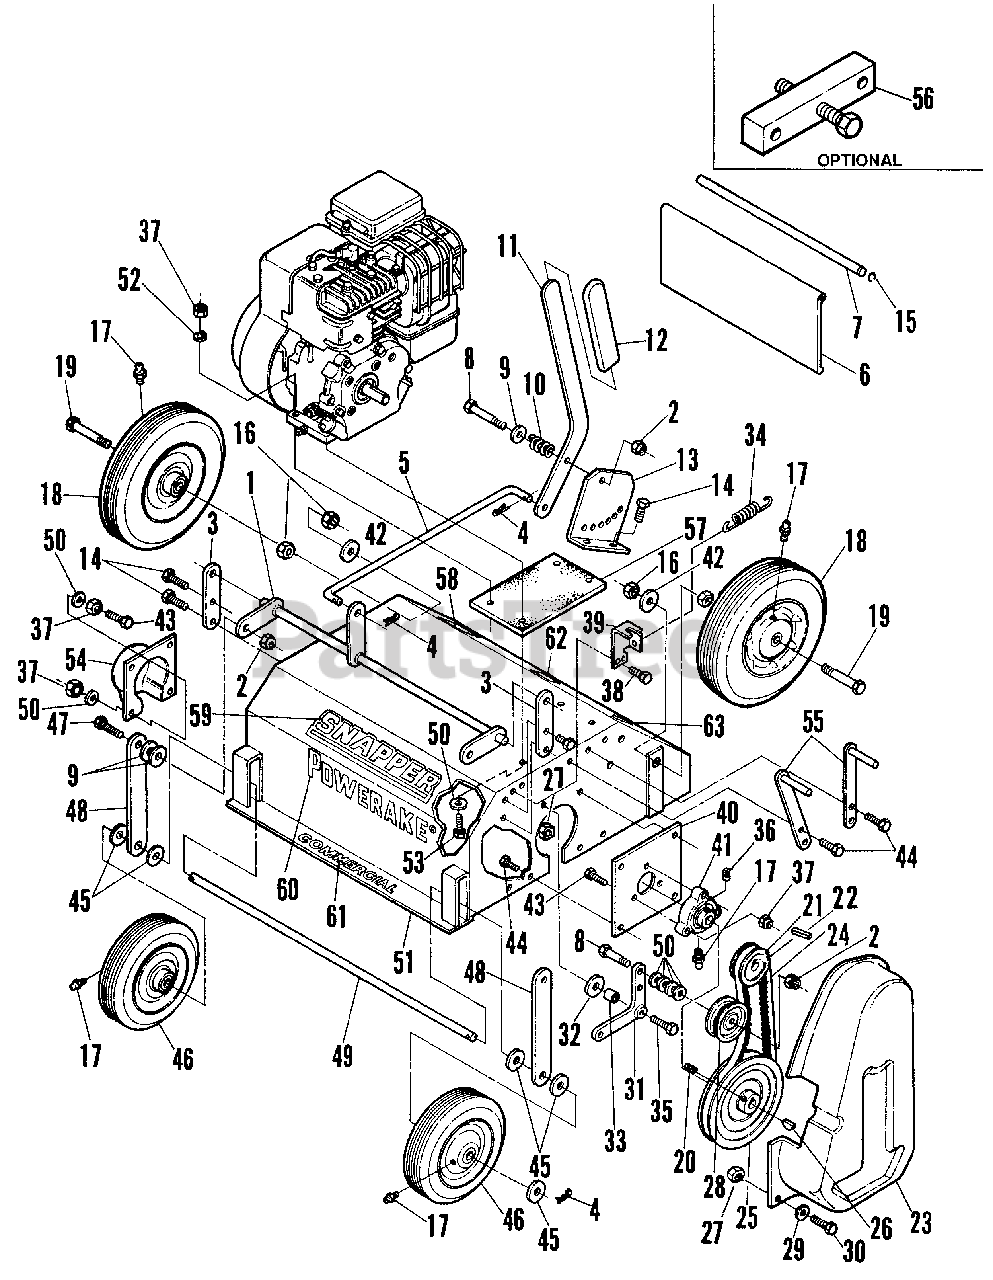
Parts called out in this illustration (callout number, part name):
1	ROD, Height Adjustment, Complete
2	NUT, 3/8-16 Hex Nyloc
3	ARM, Pivot
4	PIN, 1/8 x 3/4" Cotter
5	ARM, Linkage
6	DEFLECTOR
7	ROD, Deflector
8	SCREW, 3/8-16 x 2" Hex Head Cap, Grade 5
9	WASHER, 3/8" Standard Flat
10	SPRING, Compression
11	ADJUSTMENT LEVER w/Grip
12	GRIP, Adjustment Lever
13	GAUGE, Adjustment
14	SCREW, 3/8-16 x 1" Hex Head Cap, Grade 5
15	RING, 5/16 External Retaining
16	NUT, 5/8-11 Hex Jam
17	FITTING, 1/4-28 Straight Grease
18	REAR WHEEL, 10" w/Grease Fitting. (7-6998)
19	SCREW, 5/8-11 x 4" Hex Head Cap, Grade 2
20	SCREW, 5/16-18 x 3/8" Socket Head Set
21	PULLEY
22	KEY, 3/16" Square x 1-3/4" Machine
23	BELT GUARD
24	BELT
25	PULLEY, 7"
26	KEY, #9/606 Woodruff
27	NUT, 1/4-20 Hex Nyloc
28	PULLEY, Idler, 3/8" ID, 2.75" OD, 7/8" Wide
29	WASHER, 1/4" Standard Flat
30	SCREW, 1/4-20 x 1/2" Hex Head Cap, Grade 5
31	BELL CRANK
32	SPACER
33	BUSHING, Powdered Metal
34	SPRING
35	SCREW, 3/8-16 x 1-1/2" Hex Head Cap, Grade 5
36	SCREW, #10-32 x 1/4" Socket Head Set
37	NUT, 5/16-18 Hex Nyloc
38	SCREW, 1/4-20 x 5/8" Hex Head Cap, Grade 5
39	BRACKET, Cable
40	END PLATE
41	FLANGE BEARING w/Set Screws (7-7679)
42	WASHER, 5/8" Split Lock
43	TAPBOLT, 5/16-18 x 1-1/4" Hex Head
44	SCREW, 5/16-18 x 3/4" Hex Head Cap, Grade 2
45	WASHER, 1/2" Flat
46	FRONT WHEEL, 8" w/Grease Fitting. (7-6998)
47	SCREW, 3/8-16 x 1-1/4" Hex Head Cap, Grade 2
48	LIFT ARM
49	FRONT AXLE
50	WASHER, 5/16" Standard Flat
51	BODY w/DECALS, Powerake
51	BODY w/DECALS, Powerslice
52	WASHER, 5/16" Split Lock
53	SCREW, 5/16-18 x 1-3/4" Hex Head Cap, Grade 5
54	GUARD, Shaft
55	GUIDE, Belt
57	ENGINE PAD
59	DECAL, Snapper
60	DECAL, Powerake
60	DECAL, Powerslice
61	DECAL, Commercial
62	DECAL, Unknown
63	DECAL, Unknown
